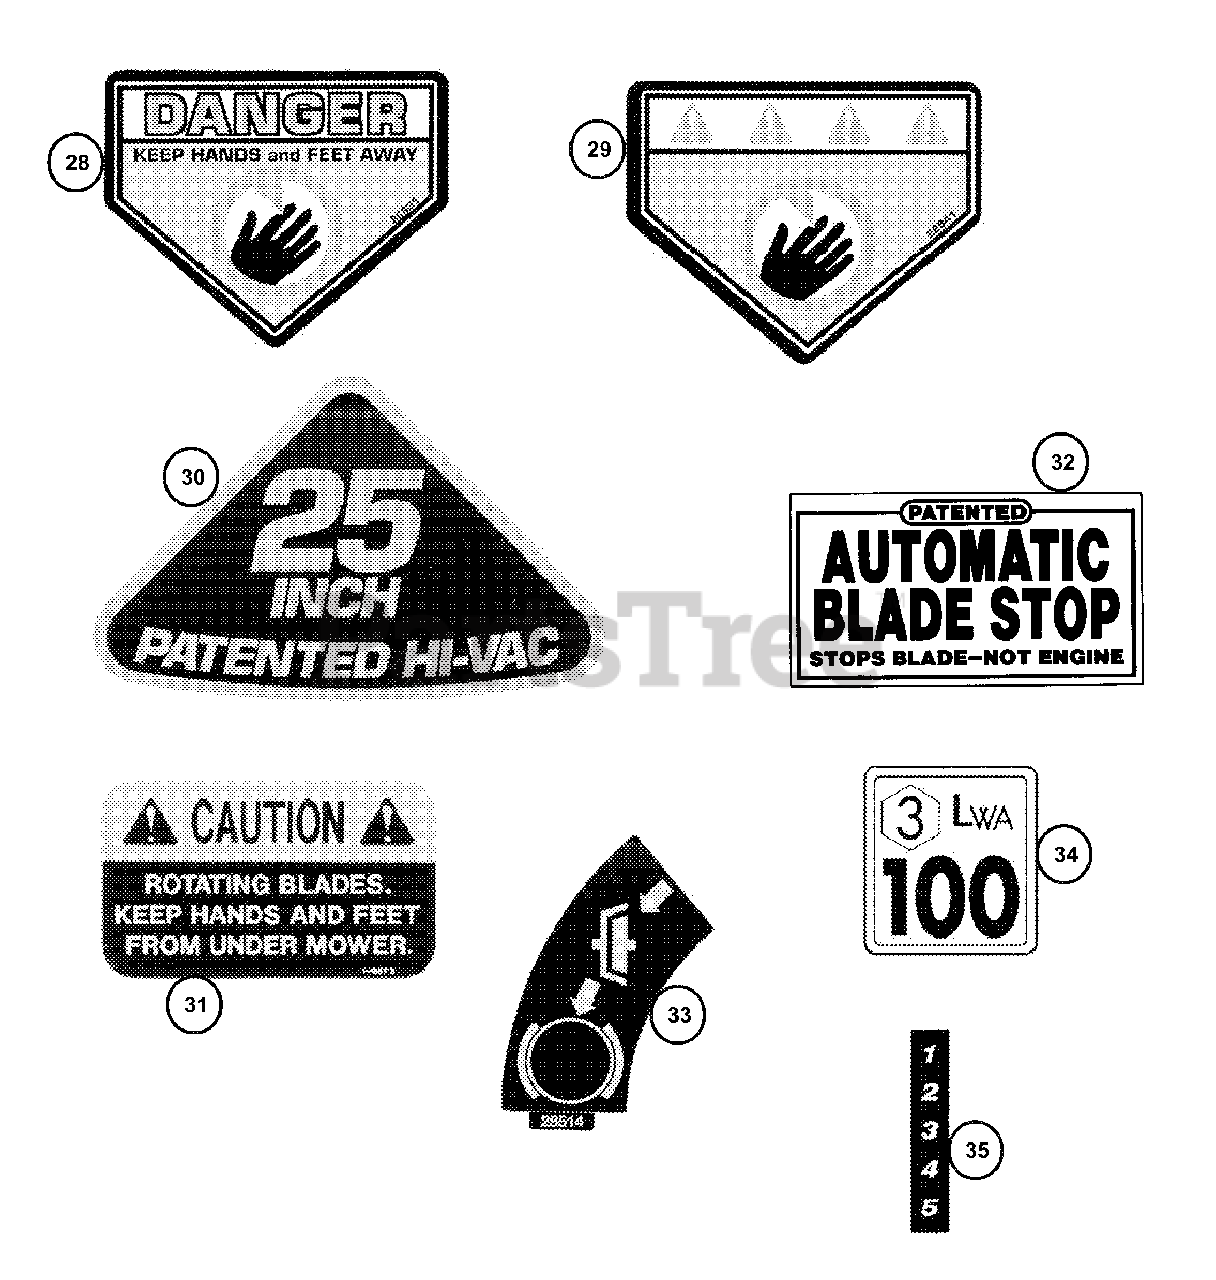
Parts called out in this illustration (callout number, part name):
28	DECAL, Danger
29	DECAL, Danger (International)
30	DECAL, 25" Patented Hi-Vac
31	DECAL, Caution (Rotating Blades)
32	DECAL, ABS Pedal
33	DECAL, Clutch/Brake (Symbol)
34	DECAL, Noise
35	DECAL, Height of Cut
